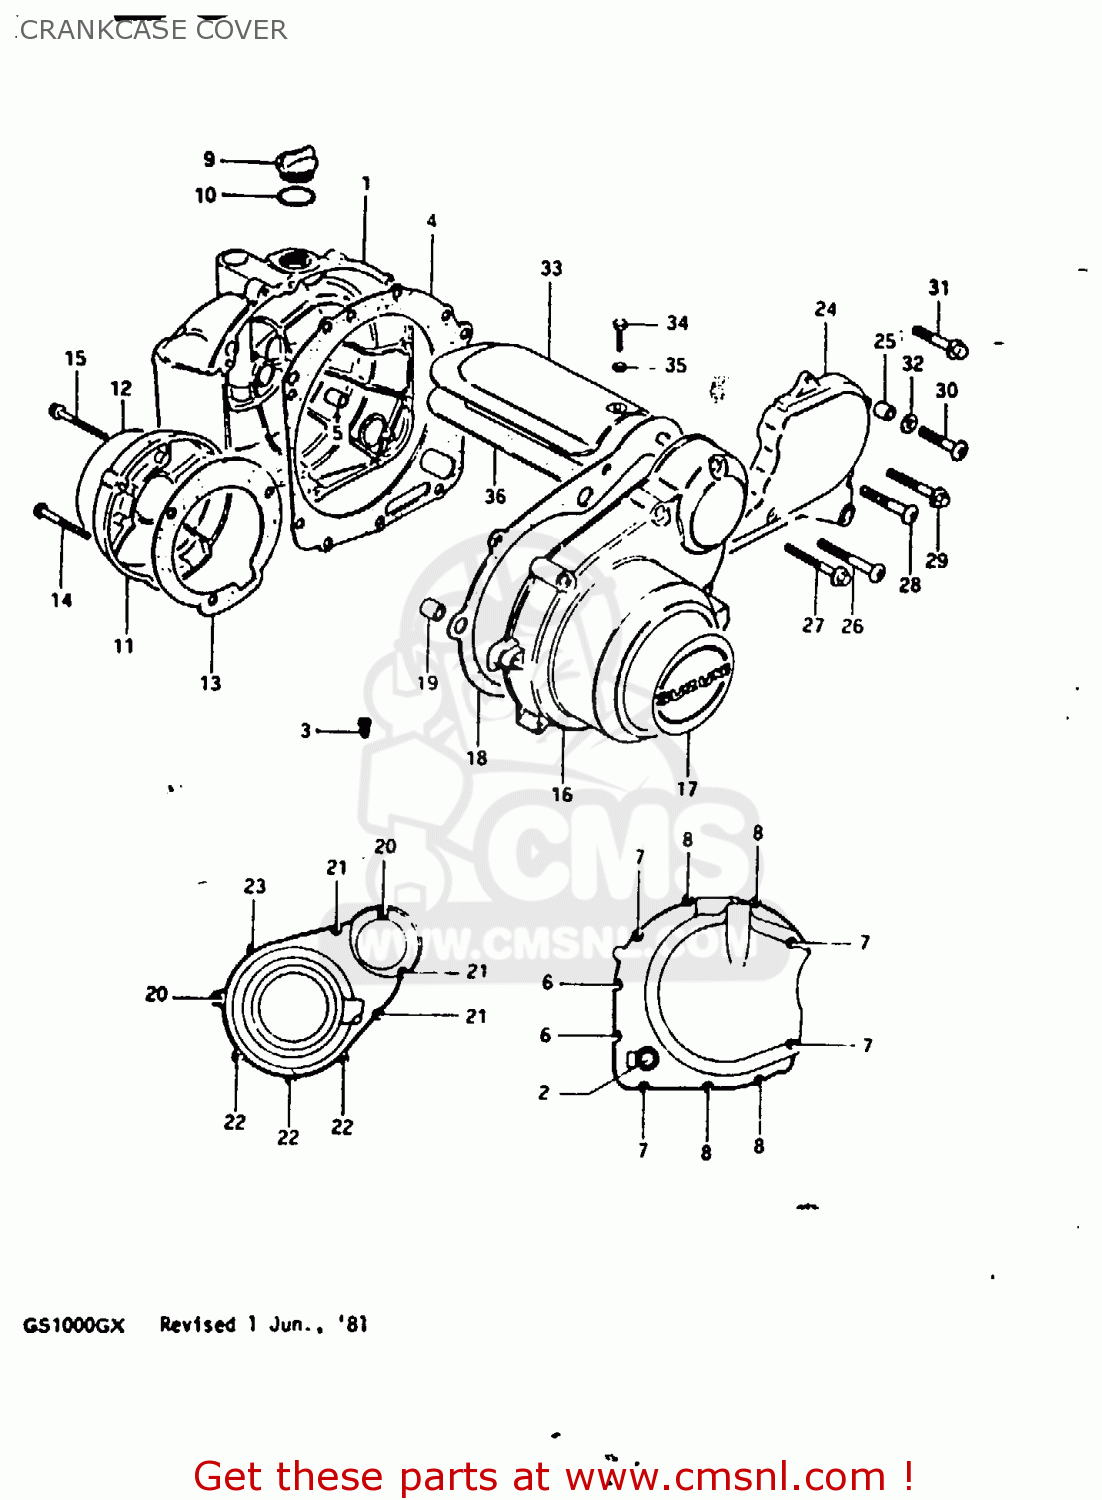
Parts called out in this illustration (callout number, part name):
1	COVER,CLUTCH
2	LENS,OIL LEVEL CHECK
3	JET
4	GASKET,MAGNETO COVER (N (MCA)
5	PIN
6	BOLT (6X35)
7	SCREW 6X30
8	BOLT
9	CAP
10	O RING(D:2.2,ID:32)
11	COVER,CONTACT BREAKER
12	EMBLEM
13	GASKET,CONTACT BREAKER COVER (NAS)
14	SCREW
15	BOLT (5*30)
16	COVER
17	EMBLEM
18	GASKET,MAGNETO COVER (MCA)
19	PIN
20	BOLT
21	SCREW
22	BOLT (6X35)
23	SCREW 6X30
24	COVER,SPROCKET
25	PIN
26	SCREW 6X30
27	BOLT (6X30)
28	SCREW
29	BOLT
30	SCREW
31	BOLT (6X20)
32	WASHER 6MM
33	COVER,STARTER MOTOR
34	BOLT
35	WASHER
36	GASKET,STARTER MOTOR COVER (MCA)
